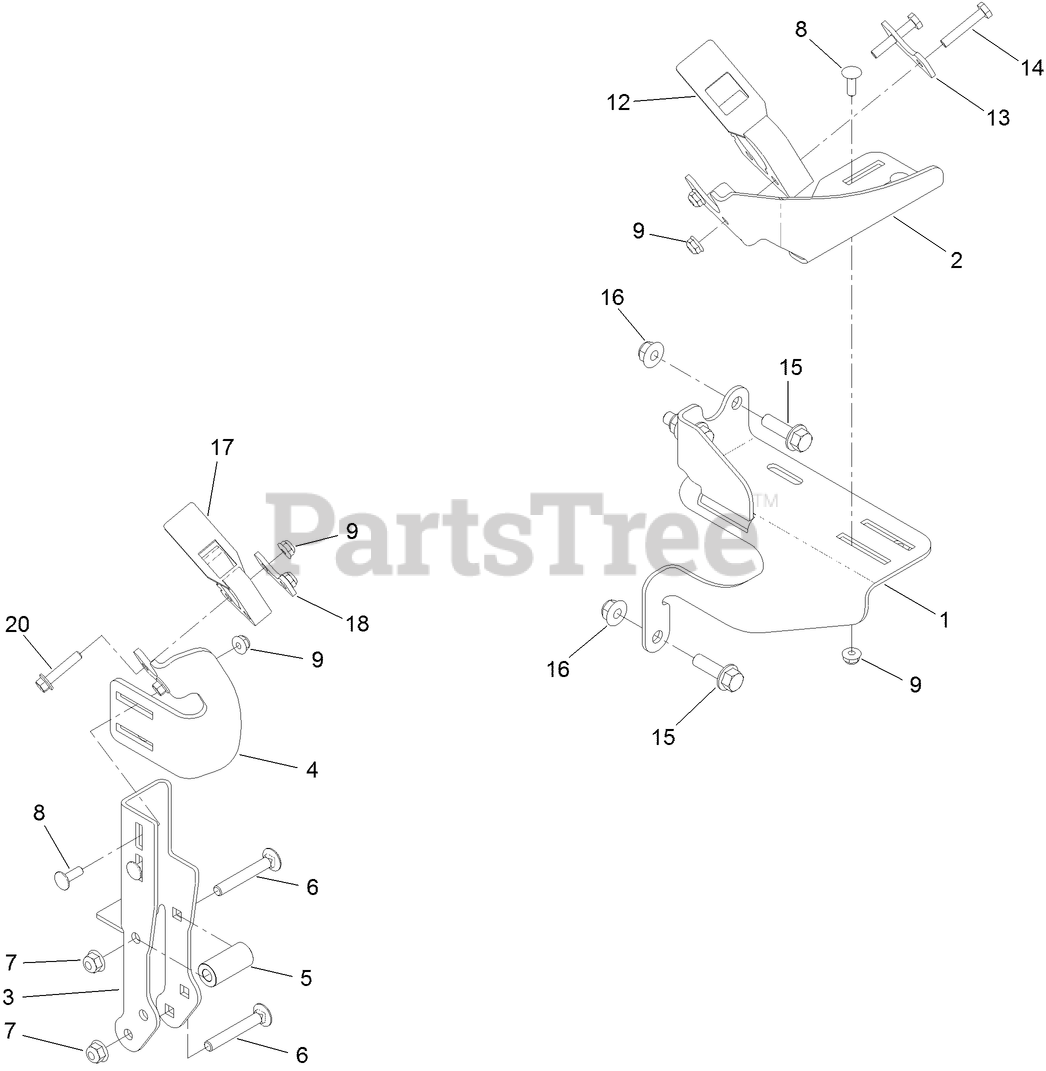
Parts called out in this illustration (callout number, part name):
1	BRACKET-WELDED
2	BRACKET-SLOT
3	BRACE-MOUNT
4	PLATE-ADJUSTMENT
5	HUB-PIVOT
6	BOLT-CARR
7	NUT-HF, NI
8	BOLT-CARR
9	NUT-HF
12	CLAMP-QUICK FIST, ORIGINAL
13	PLATE-BACKER, LARGE
14	SCREW-HH
15	SCREW-HHF
16	NUT-HF, NI
17	CLAMP-QUICK FIST, MINI
18	PLATE-BACKER, SMALL
20	SCREW-HHF
